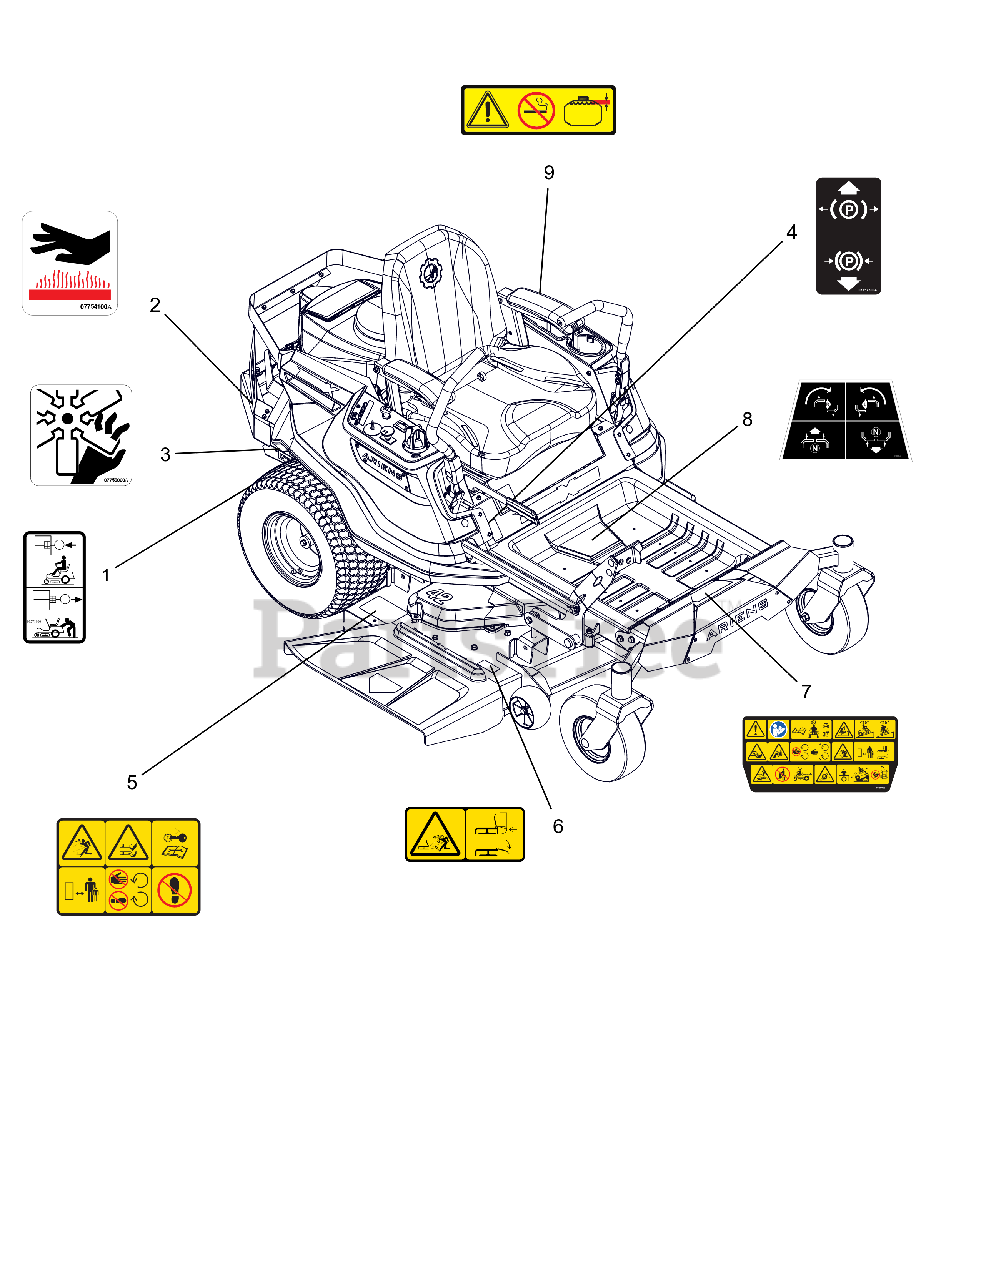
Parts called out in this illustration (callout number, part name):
1	DECAL, TRANSMISSION DISCONNECT
2	DECAL, HOT SURFACE
3	DECAL, DANGER FAN
4	DECAL, PARKING BRAKE LEVER
5	DECAL, SAFETY - MOWER DECK
6	DECAL, SAFETY - DECK GUARDING
7	DECAL, MAIN SAFETY
8	DECAL, STEERING
9	DECAL, FUEL WARNING
